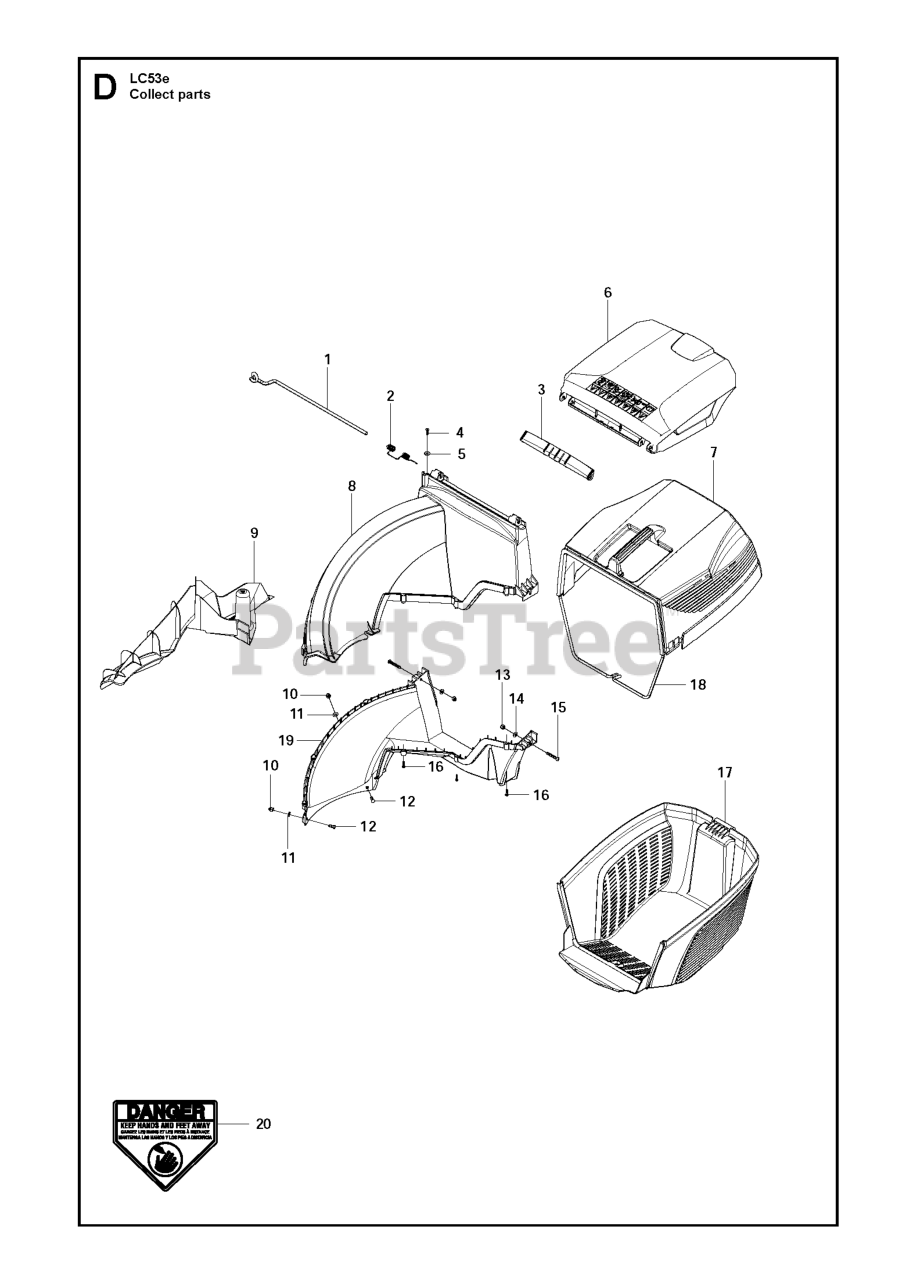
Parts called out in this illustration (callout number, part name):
1	AXLE HATCH REAR DISCHARGE
2	SPRING SAFETY FLAP A009
4	SCREW ITXPANT T50X16 ZN/FE (A
6	HATCH REAR DISCHARGE
7	GRASSBAG UPPER
16	SCREW ITXPANT T50X16 ZN/FE (A
17	GRASSBAG LOWER
20	LABEL, DANGER
